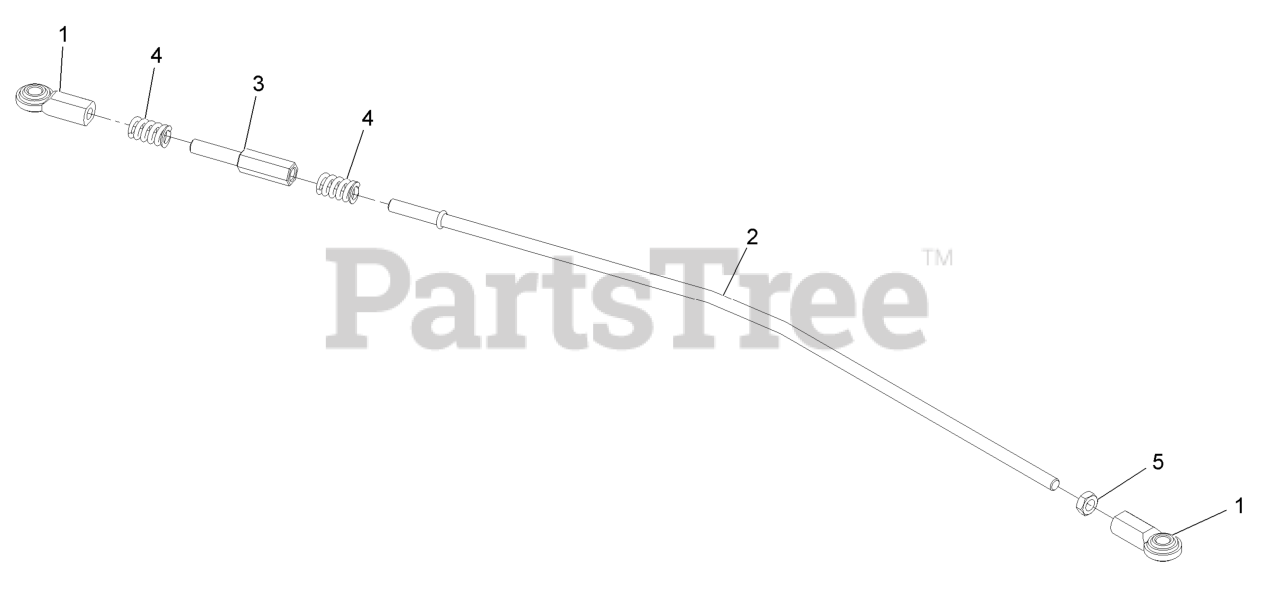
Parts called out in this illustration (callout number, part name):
1	JOINT-BALL, END
2	LINK-LOWER, MOTION CONTRO
3	ROD-ADJUSTMENT
4	SPRING, COMPRESSION
5	NUT-HJ
